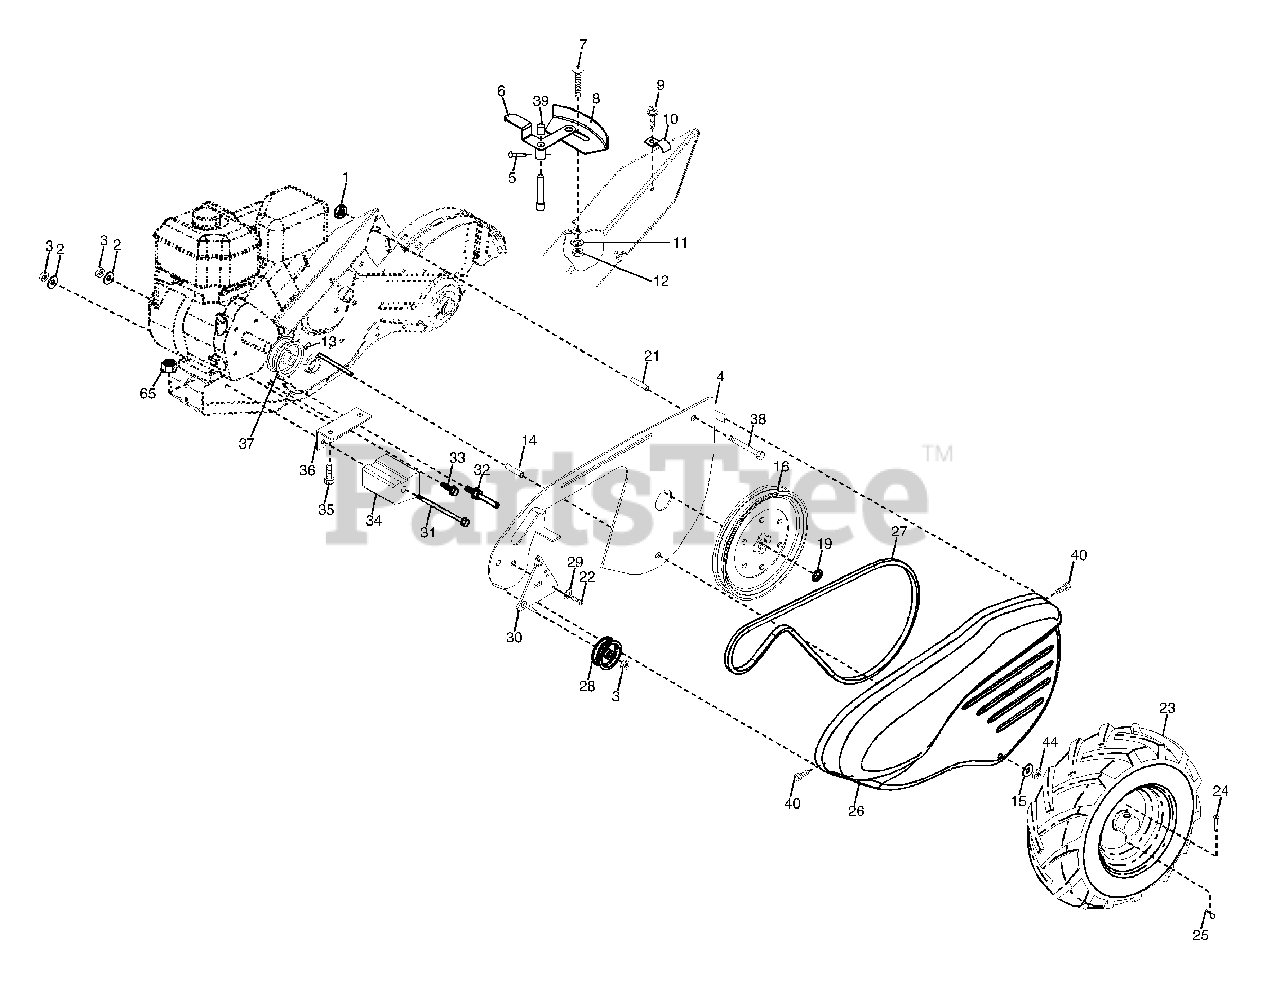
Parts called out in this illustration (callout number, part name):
1	Nut, Keps 5/16-18
2	Washer, Lock 3/8
3	Nut, Hex 3/8-16
4	Shield, Inner Belt Guard
5	Pin Spirol Flared
6	Lever, Shift
7	Bolt, Carriage 1/4-20 x 1/2 Gr. 5
8	Plate, Shift Indicator
9	Screw, Hex, Washer Head, Slotted #10-24 x 1/2
10	Clip
11	Washer, Lock 1/4
12	Nut, Hex 1/4-20
13	Screw, Set, Hex 5/16-18 x 3/8
14	Spacer, Split 0.327 x 0.42 x 1.220
15	Washer 11/32 x 11/16 x 16 Ga.
16	Sheave, Transmission
19	Ring, Retainer
21	Spacer, Split 0.327 x 0.42 x 2.09
22	Bolt, Fin Hex 5/16-24 x 1/2
23	Tire
23	Rim
23	Tire Valve
24	Rivet, Drilled
25	Clip, Hairpin
26	Guard, Belt
27	Belt, V
28	Pulley, Idler
29	Ring, Klip
30	Bracket, Idler
31	Bolt, Hex 5/16-16 x 12
32	Shaft, Idler Arm
33	Bolt, Hex 3/8-16 x 1
34	Counterweight, L. H.
35	Bolt, Hex 5/16-18 x 1-1/2
36	Bracket, Reinforcement, L. H.
37	Sheave, Engine
38	Bolt, Fin Hex 5/16-18 x 2-3/4
39	Cap, Plunger
40	Screw Hex Wsh Slt # 10-24 x .50
44	Nut, Lock 5/16-18
65	Nut, Lock Hex Flange
